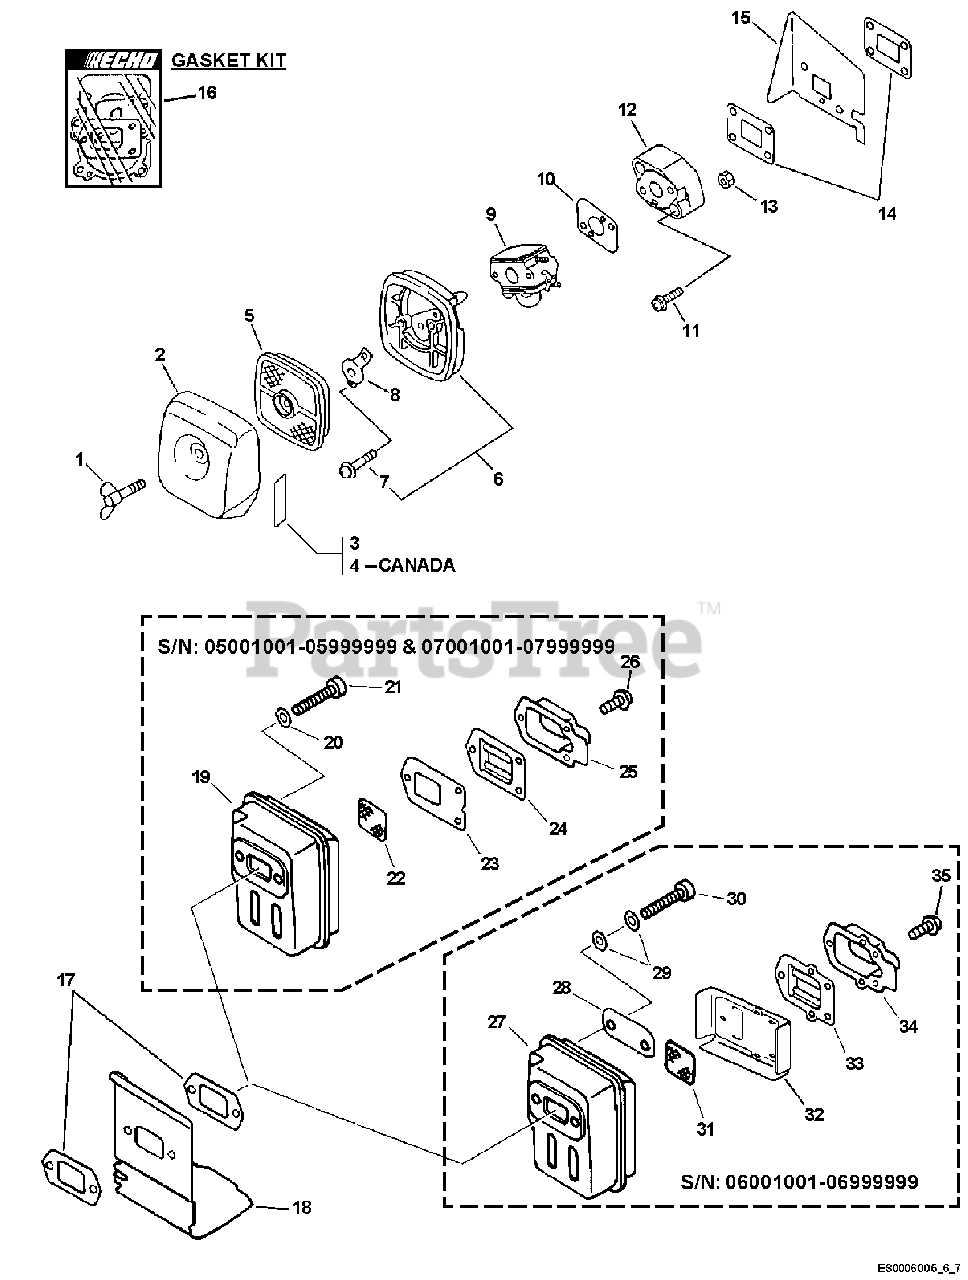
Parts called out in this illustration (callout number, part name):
1	THUMBSCREW
2	COVER, AIR FILTER - GRAY
3	LABEL - CHOKE
4	LABEL - CHOKE
5	FILTER, AIR - SINGLE LAYER
6	AIR FILTER CASE ASSY
7	SCREW - 5X65
8	PLATE, PREVENT
9	CARBURETOR
10	GASKET, INTAKE
11	SCREW - 5X22
12	INSULATOR, INTAKE
14	GASKET, INTAKE
15	SHIELD, INTAKE
16	GASKET KIT
17	GASKET, EXHAUST
18	SHIELD, EXHAUST
20	WASHER - 5
21	SCREW - 5X55
22	SCREEN, SPARK ARRESTOR
23	GASKET, EXHAUST
24	GUIDE, EXHAUST - INNER
25	GUIDE, EXHAUST - OUTER
26	SCREW - 4X10
27	MUFFLER
29	WASHER - CONICAL
30	SCREW - 5X55
31	SCREEN, SPARK ARRESTOR
32	GASKET, EXHAUST
33	GUIDE, EXHAUST - INNER
34	GUIDE, EXHAUST - OUTER
35	SCREW - 4X10
